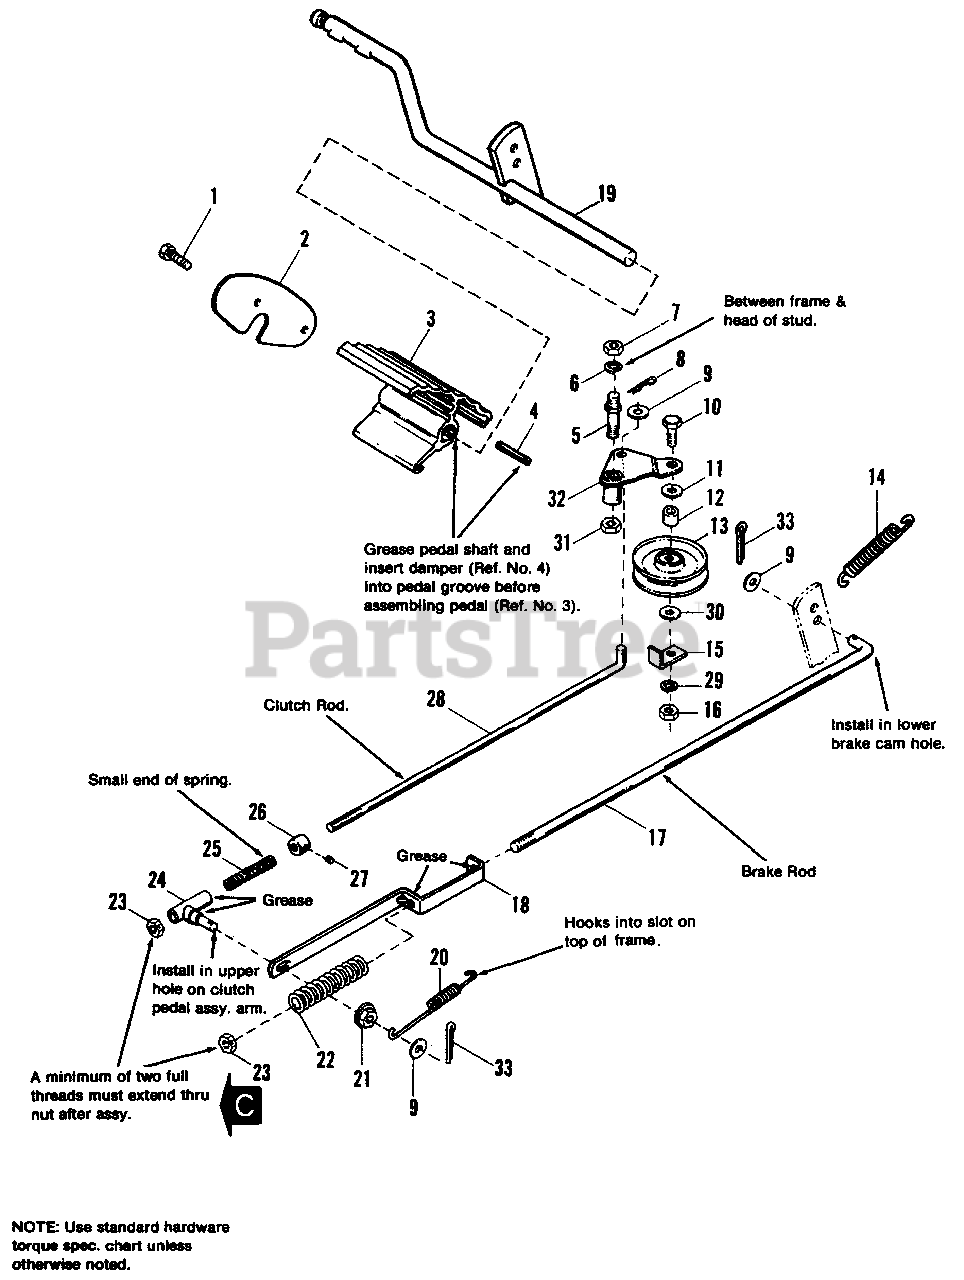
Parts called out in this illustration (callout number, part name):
1	SCREW, Hex, Taptite, 1/4-20 x 5/8
2	PLATE, End
3	PEDAL, Foot
4	DAMPER, Rubber
6	LOCKWASHER, 7/16
7	NUT, Hex, Full, 7/16-14
8	CLIP, Spring
9	WASHER, Plain, 1/4
10	CAPSCREW, Hex Hd., 3/8-16 x 1-1/2
11	WASHER, Plain, 3/8
13	PULLEY ASSY. (Incl. Ref. No. 12)
14	SPRING, Tension
15	GUARD, Belt
16	NUT, Hex, Full, 3/8-16
19	LEVER ASSY. Clutch
20	SPRING, Return
21	LOCKNUT, Hex, Flange, 5/16-18
23	LOCKNUT, Hex, Esna, 5/16-18
24	GUIDE ASSY., Rod
25	SPRING, Compression
26	COLLAR, Set
27	SETSCREW, 1/4-20 x 3/8
28	ROD, Clutch
29	LOCKWASHER, 3/8
30	WASHER, Plain, 5/16
31	LOCKNUT, Hex, 7/16-14
32	IDLER ASSY.
33	PIN, Cotter, 3/32 x 3/4
